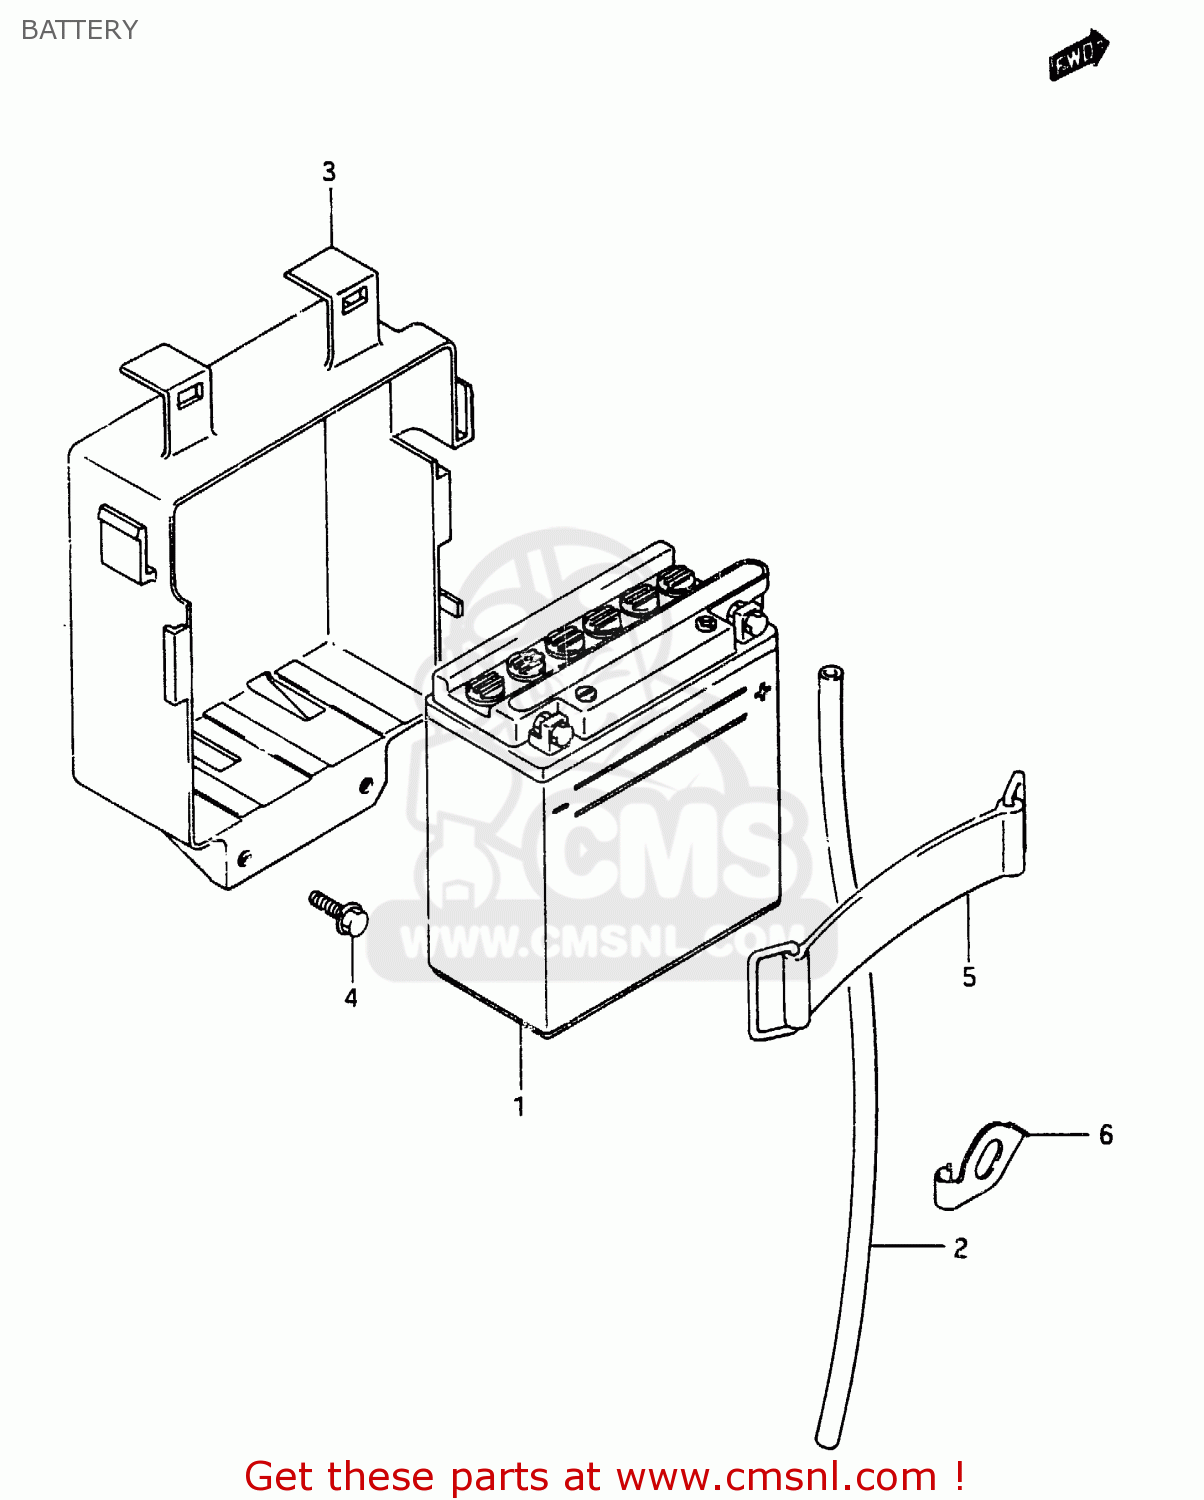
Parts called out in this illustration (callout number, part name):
1	BATTERY ASSEMBLY (12V)
2	HOSE,BATTERY EXHAUST
3	HOLDER, BATTERY
4	BOLT
5	BAND
6	CLAMP, BATTERY EXHAUST HOSE
